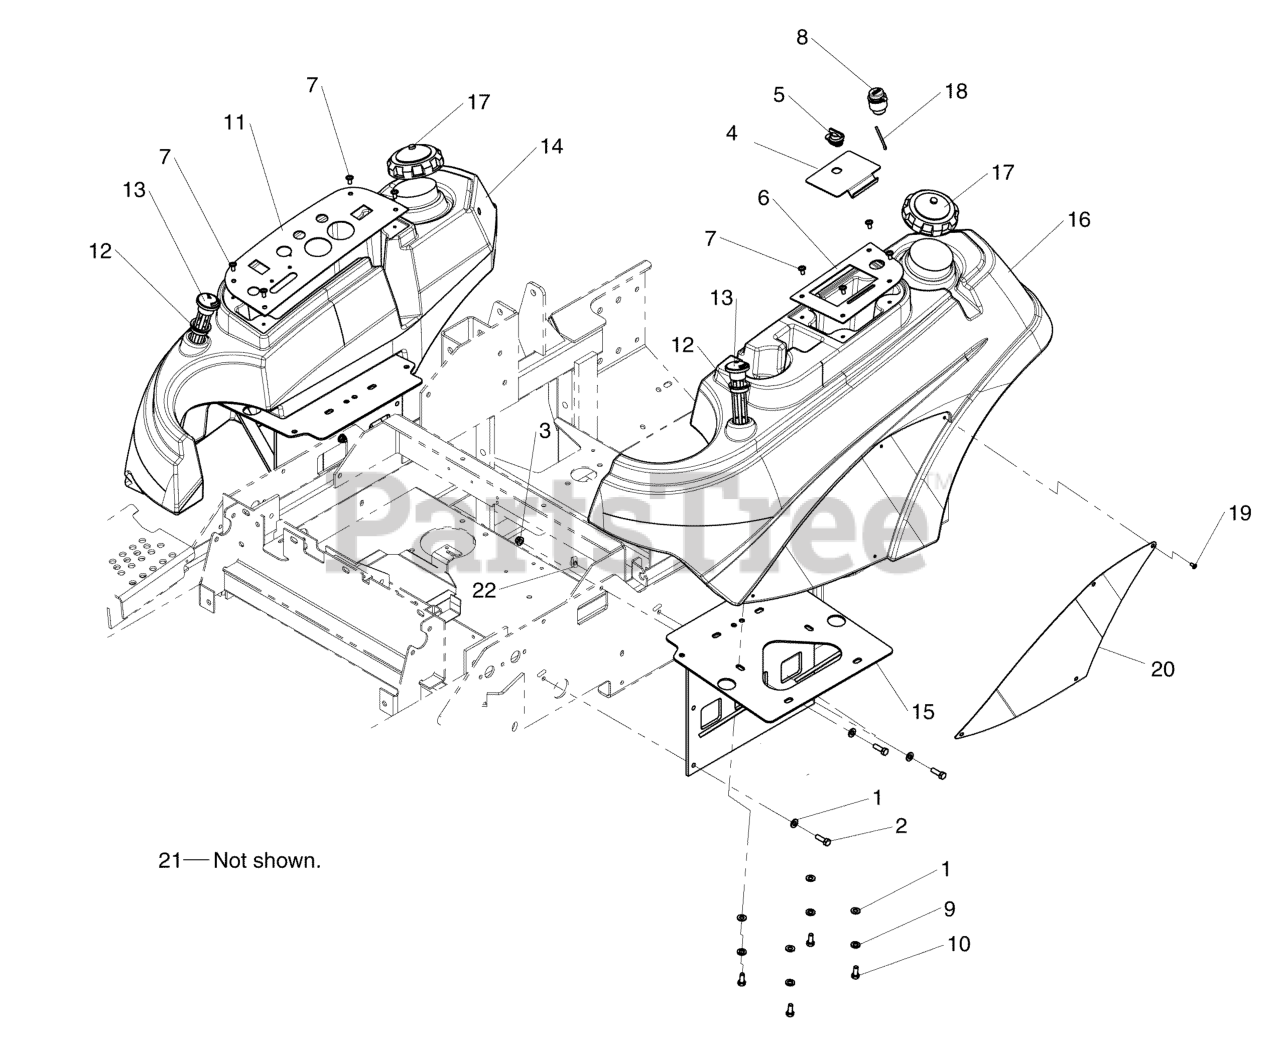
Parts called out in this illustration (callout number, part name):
1	WASHER, 5/16" SAE
2	BOLT, 5/16-18 X 1" GD5
3	NUT, 5/16-18 HEX NYLOCK FLANGE
4	COVER, CONTROL PANEL
5	LATCH, CONTROL PANEL
6	PANEL, CONTROL - LH
7	SCREW, ALLEN HEAD, 1/4-20X1/2
8	POWER, OUTLET - 12 VOLT
9	WASHER, 5/16 LOCK CZ
10	BOLT, 5/16-18 X 3/4 GD5
11	CONTROL PANEL
12	GROMMET, FUEL GAUGE
13	GAUGE, FUEL, 12
14	TANK, FUEL, DIESEL, RH
15	WELD, FUEL TANK MOUNT
16	TANK, FUEL, DIESEL, LH
17	FUEL CAP, 3.5", NON VENTED, DIESEL (GRN)
18	PIN, COTTER, 1/8 X 1-1/4
19	SCREW, Allen Head, #10-24 x 3/8"
20	PLATE, BADGE, IS4500Z
22	BODY CLIP, 5/16-18-7GA MATERIAL
